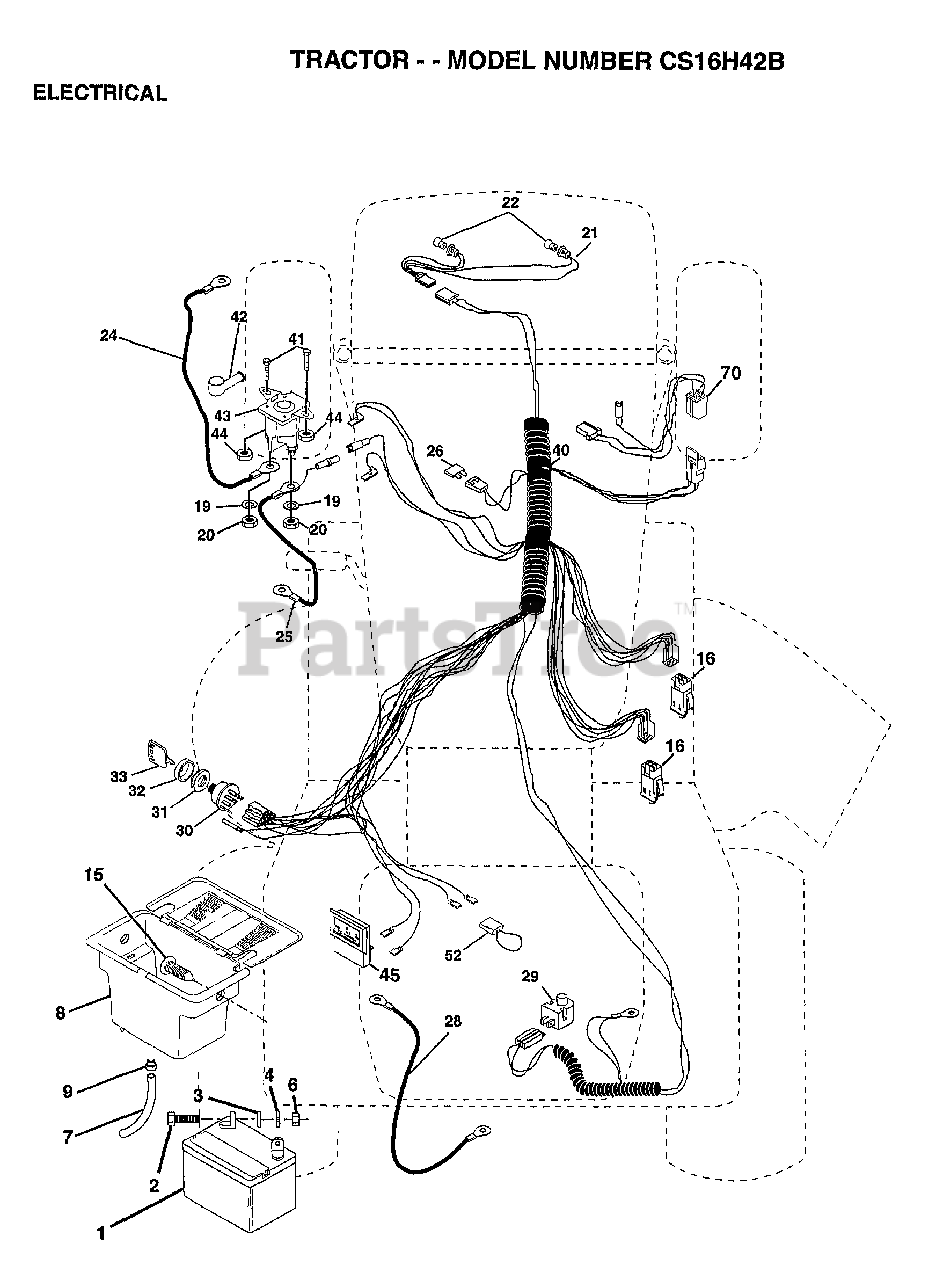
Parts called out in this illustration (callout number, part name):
2	BOLT LT
3	WASHER
4	LOCKWASHER
7	TUBE T
8	"CASE,BATTERY.MECH"
9	HOSE CLAMP T
15	FASTNER.SNAP-IN
16	SWITCH INTERLOCK
20	NUT
21	"HARNESS,LIGHT SOC"
22	HEADLAMP BULB
24	"CABLE T, BATTERY"
25	CABLE.BTRY.6GA.RD
26	FUSE HYT
28	CABLE T
29	SWITCH SEAT
30	SWITCH IGN 4POS
31	NUT IGNITION
32	COVER KEY SWITCH
33	KEY
40	HARNESS-IGNITION
41	BOLT HXHD FIN
44	NUT HXKEP 1/4X20
52	PROTECTION LOOP
70	HARNESS ENG DUAL
